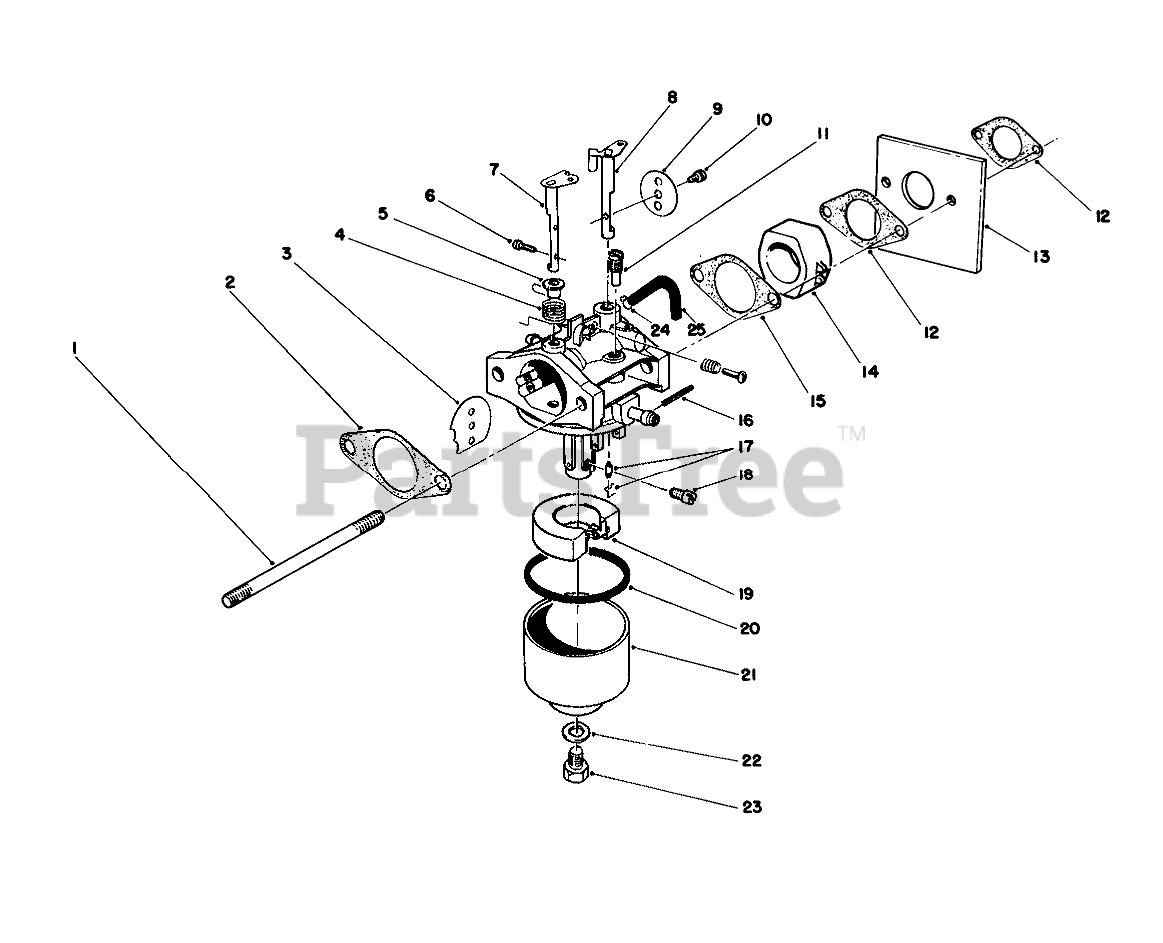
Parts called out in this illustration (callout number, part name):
1	STUD-CARBURETOR
2	GASKET-AIR CLEANER
3	PLATE
4	SPRING
5	BUSHING
6	SCREW
7	SHAFT-CHOKE
8	SHAFT
9	PLATE
10	Screw-Throttle
11	PILOT JET
12	GASKET
13	SHIELD-CARBURETOR
14	INSULATOR-CARBURETOR
15	GASKET-CARB
16	Pin
17	NEEDLE
18	JET-MAIN
19	FLOAT
20	GASKET
21	Bowl-Float
22	GASKET
23	Bolt
24	CLAMP
25	VENT TUBE
